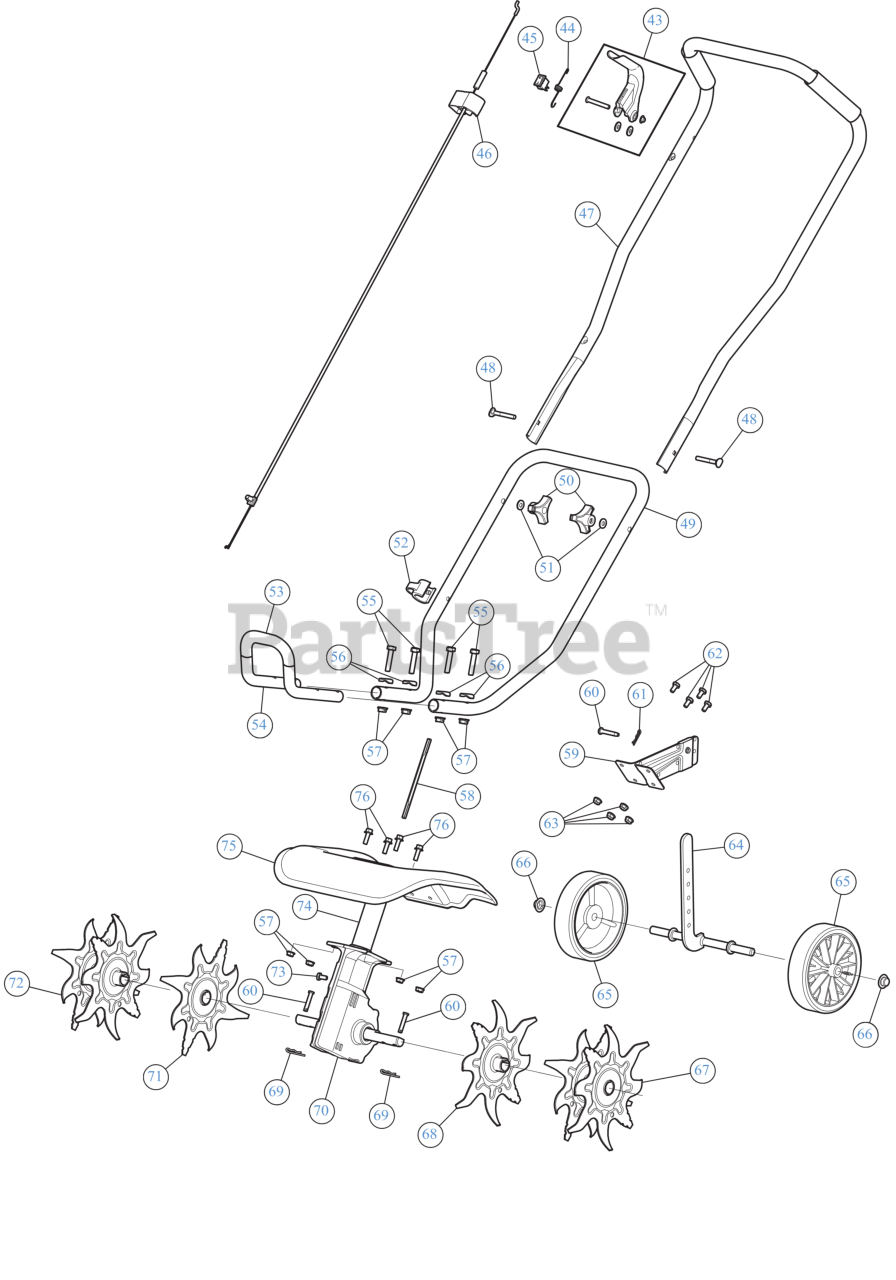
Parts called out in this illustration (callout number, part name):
43	THROTTLE LVR W/HDW
45	SW, MOMENTARY ON/O
46	THROTTLE CABLE
47	HANDLE UPR CULT
48	BOLT, CARRIAGE CRV
50	KNOB, 3-PRONG ¼ "-
51	WASH, FLAT SPECIAL
52	CABLE GUIDE
53	FOAM GRIP - 9"
54	FRONT HANDLE
55	SCREW 5/16-18 x 1.5 LG
56	SADDLE WASHER
57	LOCK NUT 1/4
58	SHAFT-FLEX
59	TAILPIECE BRACKET ASSEMBLY
60	CLEVIS PIN
61	BOW TIE COTTER PIN 1/4-5/16
62	SCREW 1/4-20X.5 GR5
63	LOCK NUT 1/4
64	BRACKET ASSEMBLY
65	WHEEL 5-1.5 GRAY
67	TINE ASSEMBLY (LH)
68	TINE ASSEMBLY (LH)I (RH)O
69	BOW TIE COTTER PIN 1/4-5/16
70	GEARBOX ASSEMBLY CULT
71	TINE ASSEMBLY (LH)O (RH)I
72	TINE ASSEMBLY (RH)
73	SCREW 1/4-20 X.500
74	BOOM ASSEMBLY CULT
75	TINE SHEILD RED
76	HEX SCREW 1/4-20X.
